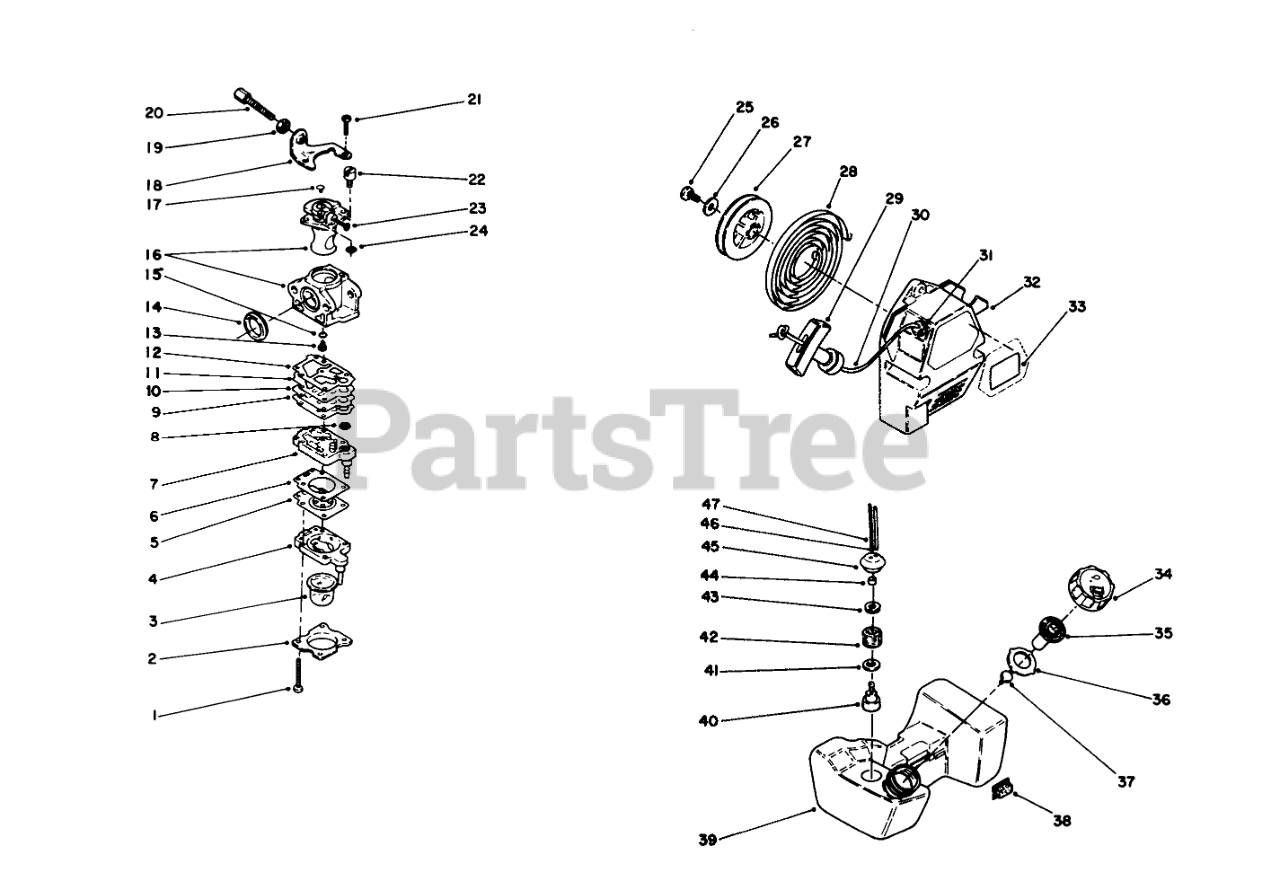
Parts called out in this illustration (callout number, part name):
1	SCREW
2	Cover-Primer
3	PRIMER PUMP
4	PRIMER BODY
5	DIAPHRAGM
6	DIAPHRAGM GASKET
7	PUMP BODY
8	SCREEN
9	PUMP GASKET
10	Plate
11	DIAPHRAGM
12	DIAPHRAM GASKET
13	MAIN JET
14	RUBBER CARB GASKET
15	MAIN JET O-RING
16	Body-Carburator (Ref.)
18	BRACKET
19	LOCKNUT
20	ADJUSTING SCREW
21	SCREW
22	Holder-Wire
23	THROTTLE VALVE
25	SCREW
26	WASHER
28	SPRING
29	Knob-Starter
30	Rope-Recoil
31	GUIDE
32	Case-Starter
33	Decal-Toro
34	FUEL TANK CAP
35	BREATHER VALVE
36	PACKING
39	Tank Assembly-Fuel
40	Weight-Filter
42	Filter-Fuel
43	Washer-Seal
44	COLLAR
45	FUEL TANK GROMMET
46	TUBE, FUEL
47	RETURN FUEL HOSE
